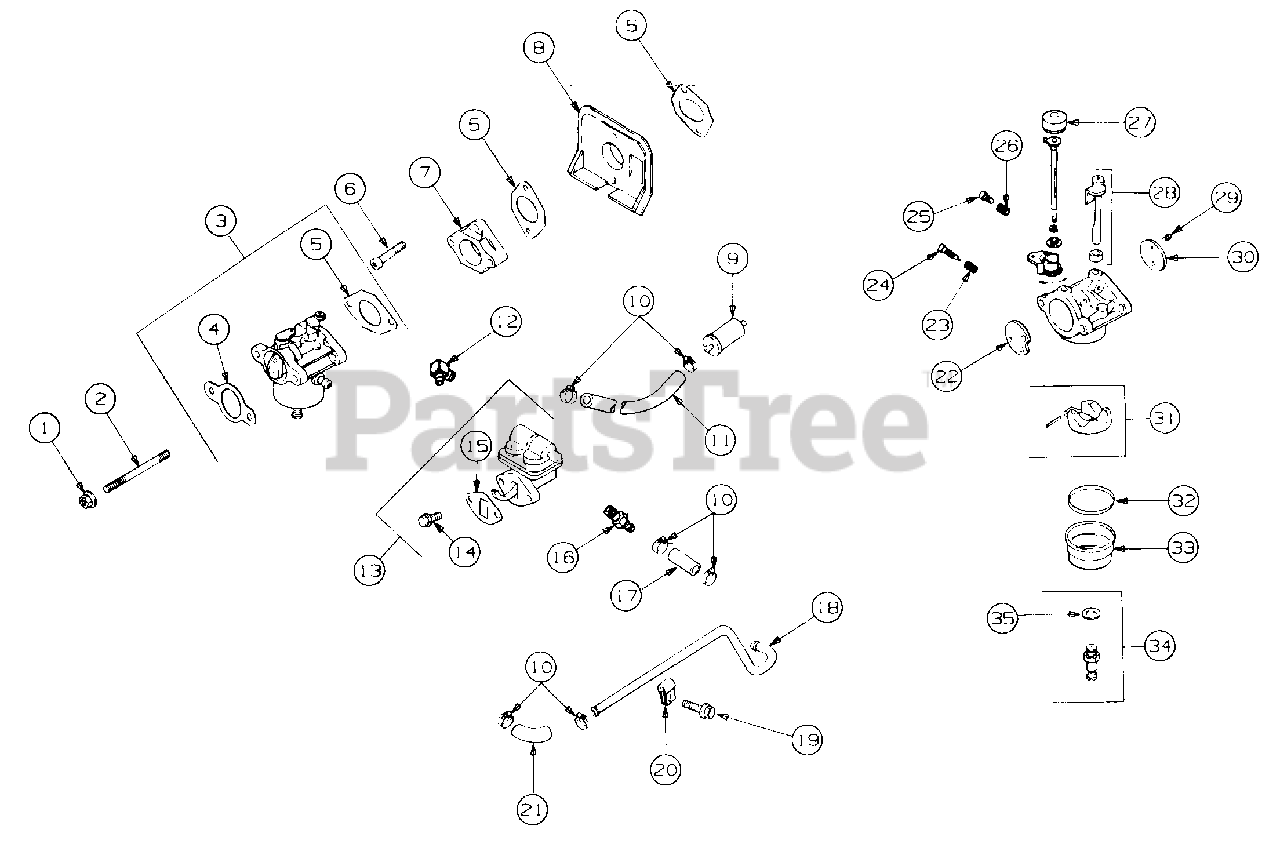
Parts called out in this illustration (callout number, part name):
1	Nut, Carburetor, M6 x 1.0
2	Stud, Carburetor, M6 x 1.0 x 72
3	Kit, Carburetor w/Gaskets
4	Gasket, Air Filter
5	Gasket, Carburetor
6	Screw, Adapter, M6 x 1.0 x 35
7	Adapter, Carburetor
8	Deflector, Heat
9	Filter, Fuel
10	Clamp, Fuel Line
11	Line, Fuel
12	Connector, Hose, 90°.
13	Kit Fuel Pump
14	Screw, Fuel Pump, M6 x 1.0 x 20
15	Gasket, Fuel Pump
16	Connector, Straight Hose
17	Line, Fuel, 3"
18	Line, Fuel, Metal
19	Screw, Clip, M5 x 0.8 x 10
21	Line, Fuel, 1-1/4
22	Plate, Choke
23	Spring, Idle Fuel
24	Needle, Idle Fuel Adj
25	Screw, Idle Speed Adj
26	Spring, Idle Speed
27	Cap, Choke Lever
28	Shaft, Throttle w/Lever & Seal
29	Screw, Throttle Plate
30	Plate, Throttle
32	Gasket, Bowl
34	Kit, Needle w/Gasket
35	Gasket, Bowl Ret Screw
